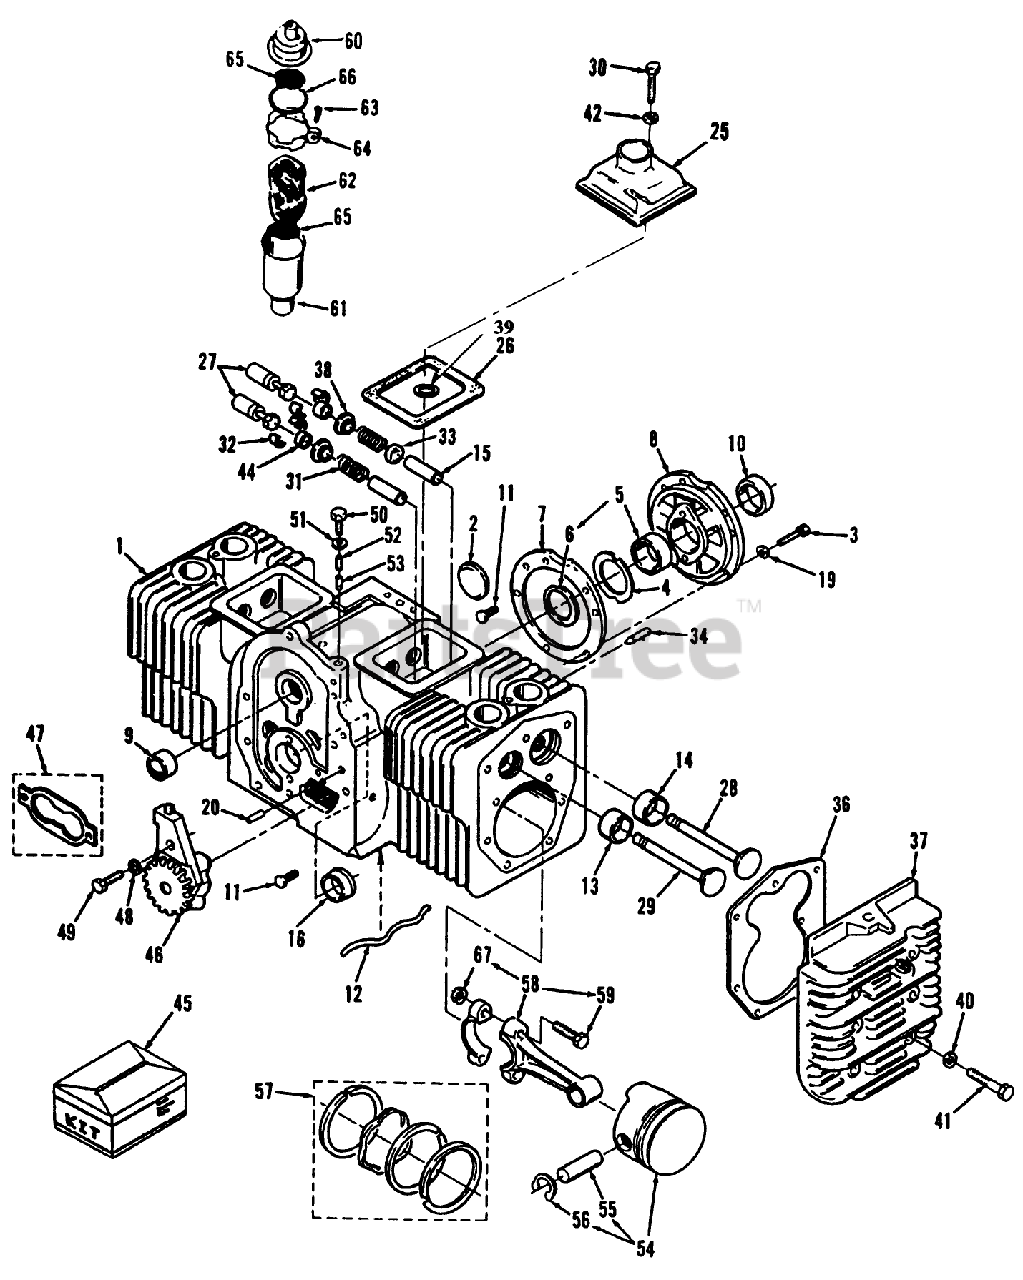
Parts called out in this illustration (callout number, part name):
5	Bearing-Crankshaft, Rear (Includes Thrust Washer)
7	GASKET
8	PLATE-BEARING, REAR
13	Insert-Valve Seat, Exhaust
14	Insert-Valve Seat, Intake
16	Bearing-Crankshaft, Front, Flanged
26	GASKET
27	Tappet-Valve
45	Kit-Gasket
54	Piston (Includes Pin Retaining Rings)
57	Kit-Ring, Piston
58	Rod-Connecting (Includes Bolt Nut)
61	TUBE-BREATHER
62	FILTER
63	SCREW-TAPPING, ROUND HEAD
66	SEAL - O-RING
